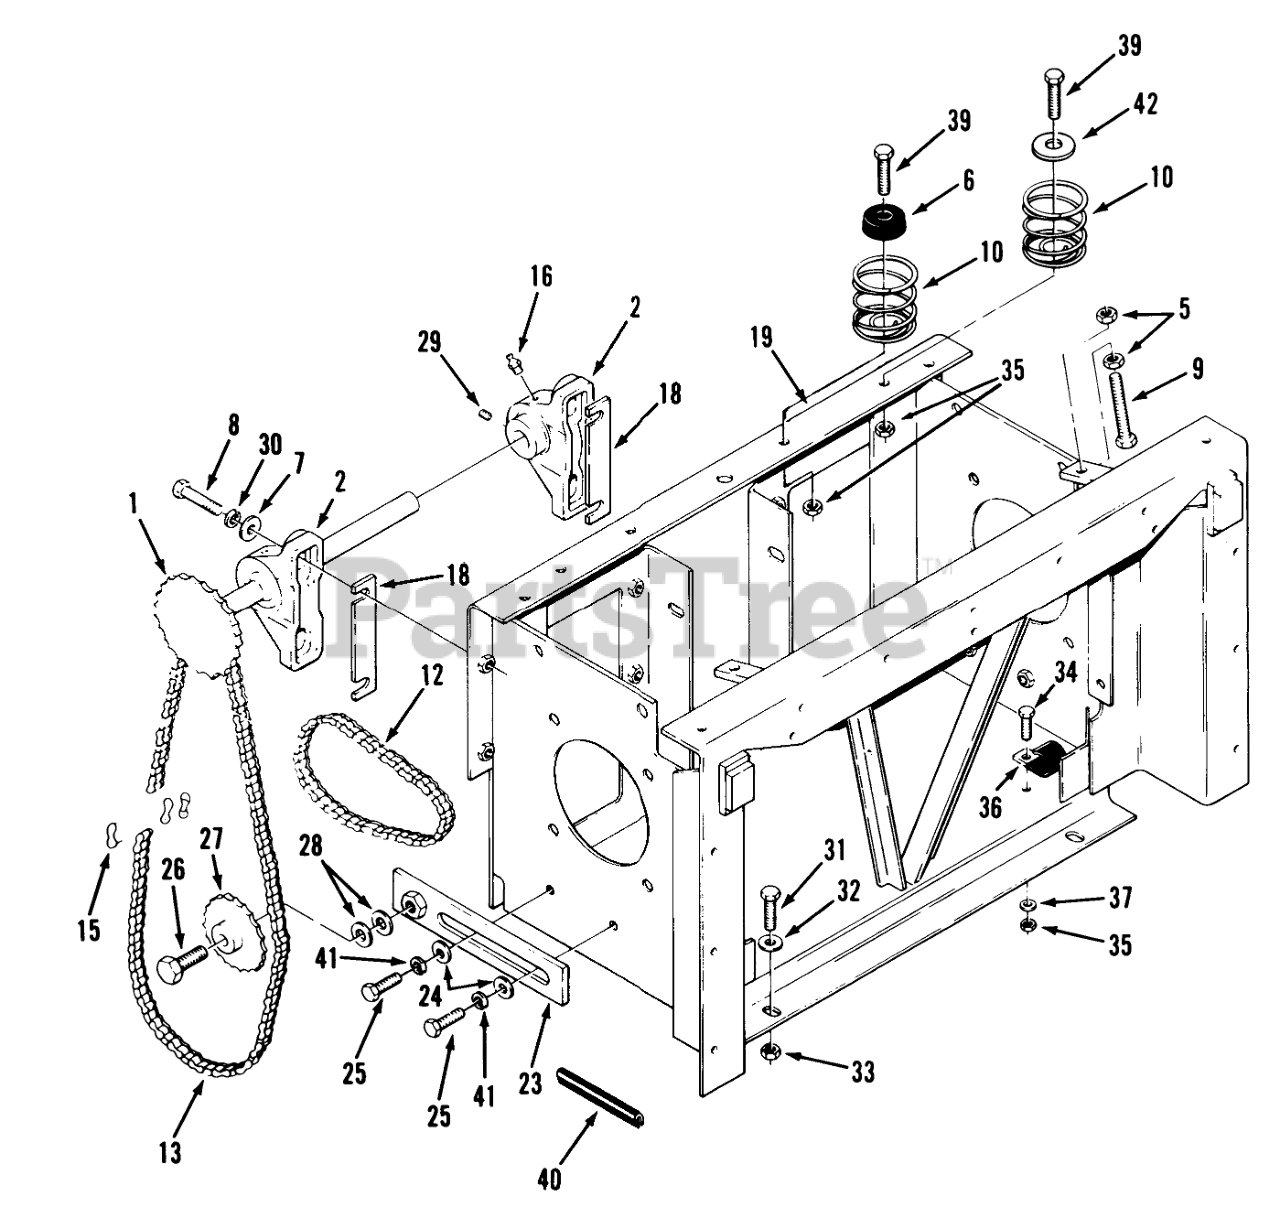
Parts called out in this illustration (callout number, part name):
1	ASSY-JACKSHAFT PLT
2	Bearing-Pillow Block (Incl. Items 16 & 29)
5	NUT-HEX
6	BUMPER
7	WASHER-FLAT
8	SCREW-HH
9	SCREW-HH
10	SPRING-SEAT NYLON
12	CHAIN-#50 PRIMARY
13	ROLLER-CHAIN #50 SEC
15	CONNECTING LINK
16	Fitting-Grease
18	SHIM-PILLOW BLOCK
19	WLDMT-FRAME TRANS B
23	ASSY-CHAIN TENSIO B
24	WASHER
25	SCREW-HH
26	SCREW-HH
27	IDLER SPROCKET 20288
28	WASHER-FLAT
29	SCREW-SET
30	WASHER-LOCK
31	SCREW-HH
32	WASHER-FLAT
33	NUT-LOCK, NI
34	SCREW-HH
35	NUT-LOCK, NI
36	CLIP
37	WASHER-PLAIN
39	SCREW-HH
40	EDGE TRIM
41	WASHER-LOCK
42	WASHER
